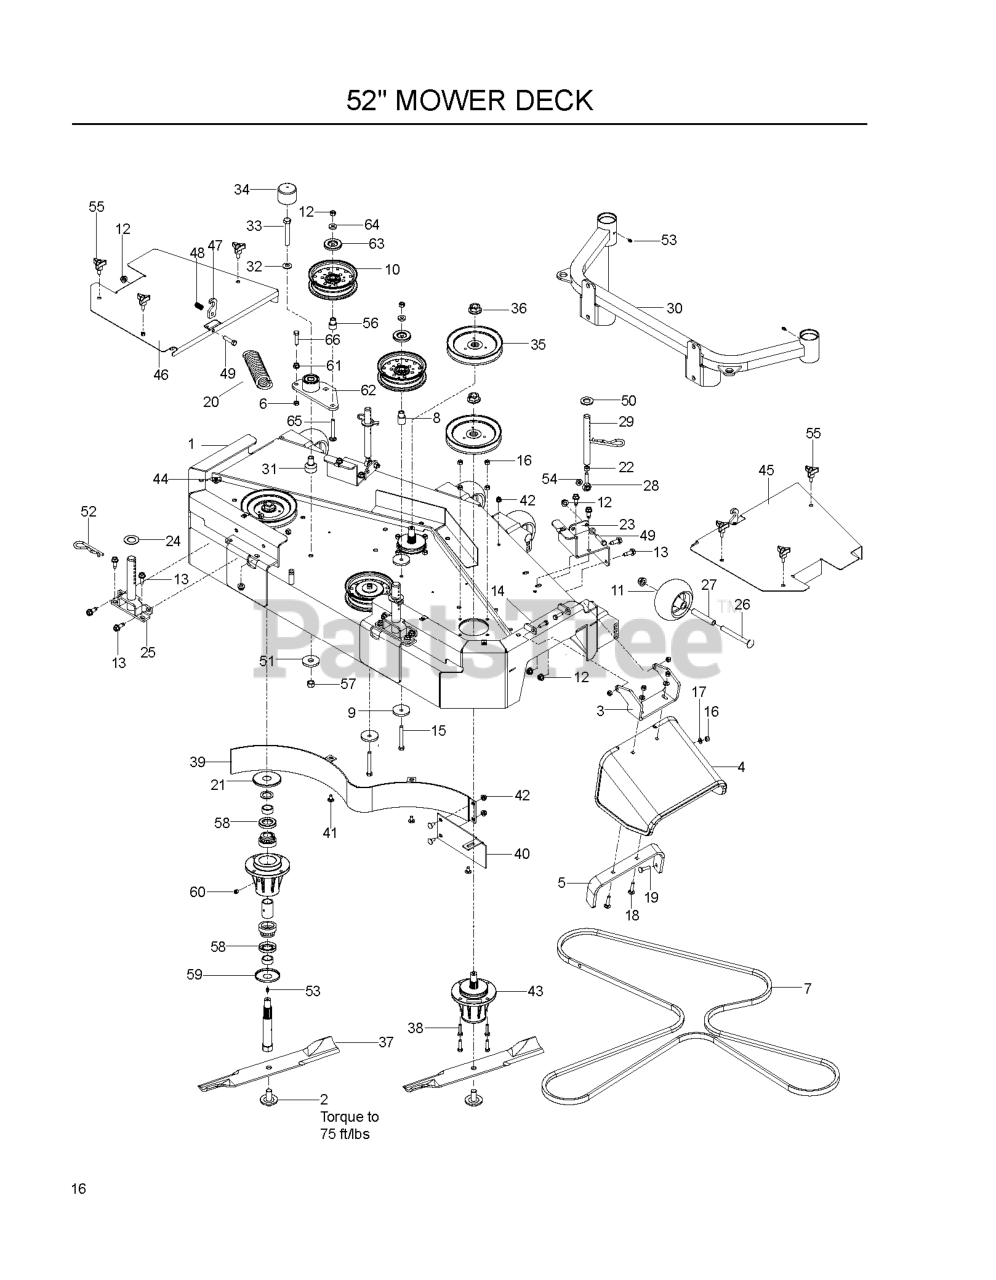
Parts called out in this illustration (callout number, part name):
1	CUTTER DECK w/DECALS
2	BLADE BOLT/WASHER
3	HINGE CHUTE - BLACK
4	CHUTE, RUBBER DISCHARGE WB
5	BRKT, REINF-CHUTE WB
6	NUT 3/8-16 HEX JAM
7	BELT, DECK
8	IDLER BUSHING
9	SPINDLE WASHER
10	IDLER PULLEY
12	NUT 3/8-16 HEX FLG NYLOC ZD
13	BOLT 3/8-16 X 1.0
14	HCS 5/16C X 1
15	HCS 3/8C X 3
16	NUT 5/16 NYLOC
17	FLAT WASHER 5/16 SAE
18	RHSNB 5/16-18 X 1-1/2 GR 5 ZD
19	BOLT, CARRIAGE 5/16X1-1/4
21	TOP DUST CAP
23	SUPPORT - FRONT, LH
26	RHSNB 1/2-13 X 4.75 GR5 ZD
28	ROD END - 3/8-24 RH
30	SUPPORT, CASTER 52 OR
31	PIVOT, BEARING
32	CONTACT BELLSPR 1/2
33	HCS 1/2C X 3 1/4
34	CAP, VINYL
35	PULLEY - 6.57
36	NUT FLANGE 3/4-16
37	BLADE OEM 18"
38	HCS 5/16C X 1 1/4
39	MAIN BAFFLE 52"
40	CENTER BAFFLE - 52"
41	CARRIAGE BOLT 5/16C X 5/8"
42	5/16-18 NYLOC FLANGE NUT
43	HOUSING ASM, 72
44	U-CLIP 5/16-18 NUT RETAINER
45	COVER, 52 RH GY
46	COVER, 52 LH GY
48	SPRING - COMPRESSION
49	HCS 3/8C X 1 1/2
50	WASHER 3/4 FLAT SAE ZD
51	WASHER, SUPPORT
54	WASHER 3/8 X 3/4 X .187 TK
55	KNOB W/STUD
56	BUSHING, IDLER
57	NUT 1/2-13 HEX NYLOC ZD
58	SHAFT SEAL
59	BOTTOM DUST CAP
60	PLUG-VENTED
61	NUT 3/8C WHIZ
62	ARM-IDLER W/BRG
63	DUST SHIELD
64	WASHER, 3/8 THICK
65	RHSNB 3/8-16 X 2.75
66	HCS 3/8-16 X 1-1/2
